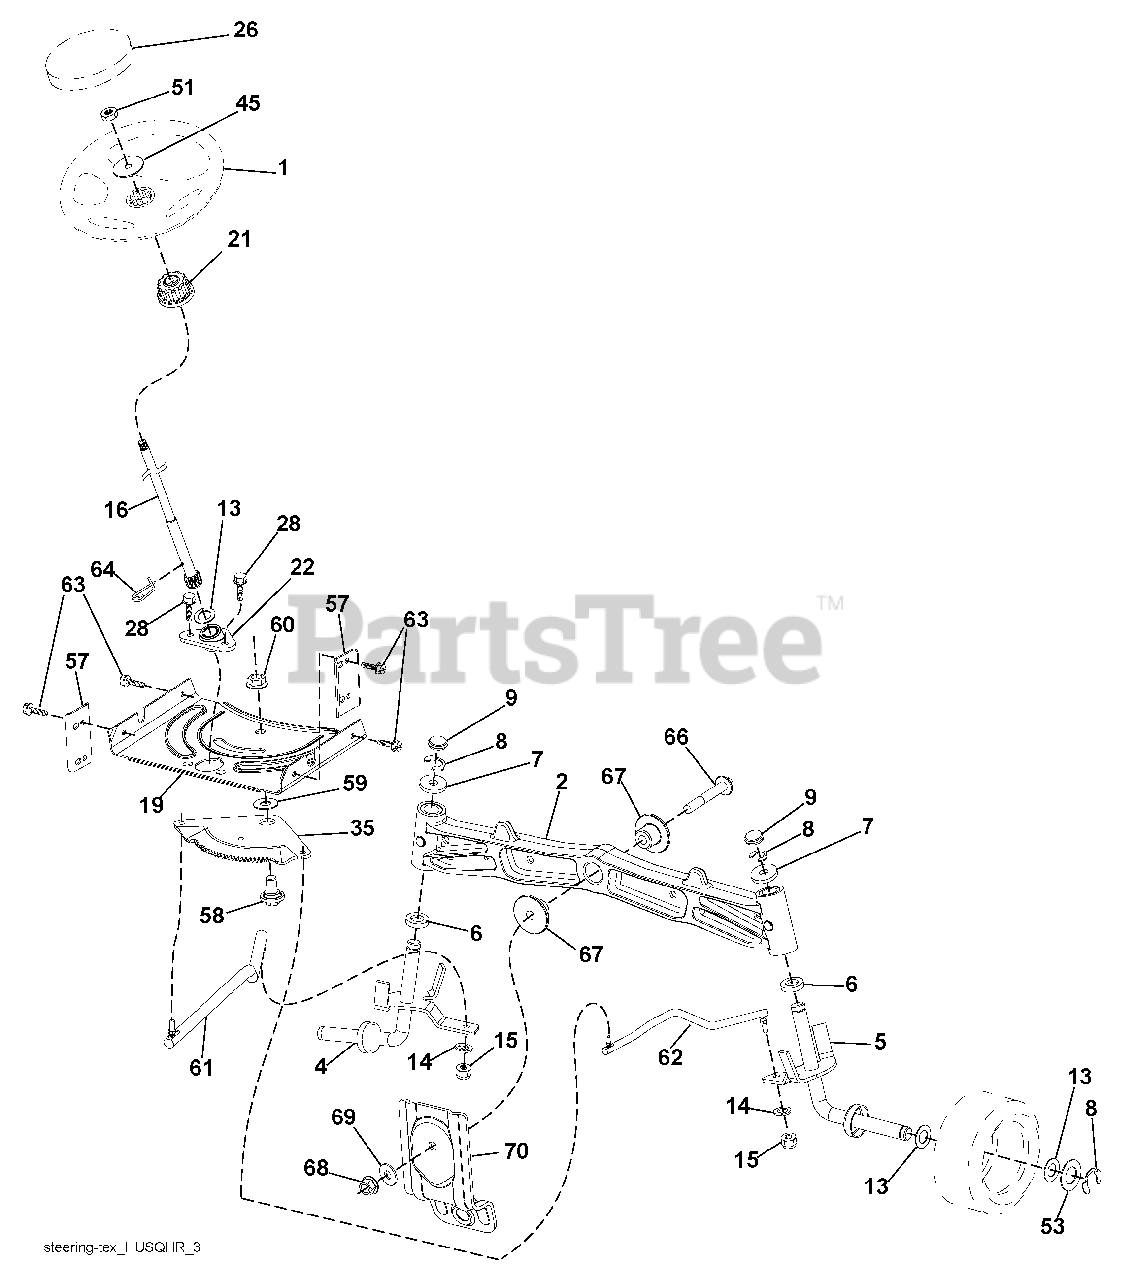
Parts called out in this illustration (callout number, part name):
1	Wheel, Steering
2	Axle Asm., Front
4	Spindle Asm., Lh
5	Spindle Asm., Rh
6	Bearing, Race Thrust Harden
7	Washer 25/32 X 1-5/8 X 16 Ga.
8	Ring, Klip #T5304-75
9	Cap, Spindle
13	Washer 25/32 X 1-1/4 X 16 Ga.
14	Washer, Lock Hvy Hlcl Spr 3/8
15	Nut, Crown Lock 3/8-24 Unf
16	Shaft Steering
19	Plate Steering
21	Adapter, Wheel Steering
22	Strg. Supt. Lower
26	Insert, Wheel Steering
28	Screw 3/8-16 X 3/4
35	Gear, Sector Plate
45	Washer 9/16 Id X 2-3/8 Od 12 Gzin
51	Nut Hex Jam Toplock 1/2-20
53	Washer Hardened .793 X 1.637 X .060
57	Bracket Upstop
58	Bolt Shoulder Sector Pivot Cfm
59	Washer Thrust Sector Steering
60	Nut Flange Lock 5/8-11
61	Draglink, Lh
62	Draglink, Rh
63	Screw 5/16-18 X 3/4
64	Retainer Clip Spring Steering
66	Bolt Hex Fghd 7/16-14 X 3 Serr
67	Bushing Pm Front Axle
68	Nut Lock Flange 7/16-14 Gr. 5
69	Washer 1.5 X .505 X .118
70	Bracket Deck Susp. Front
